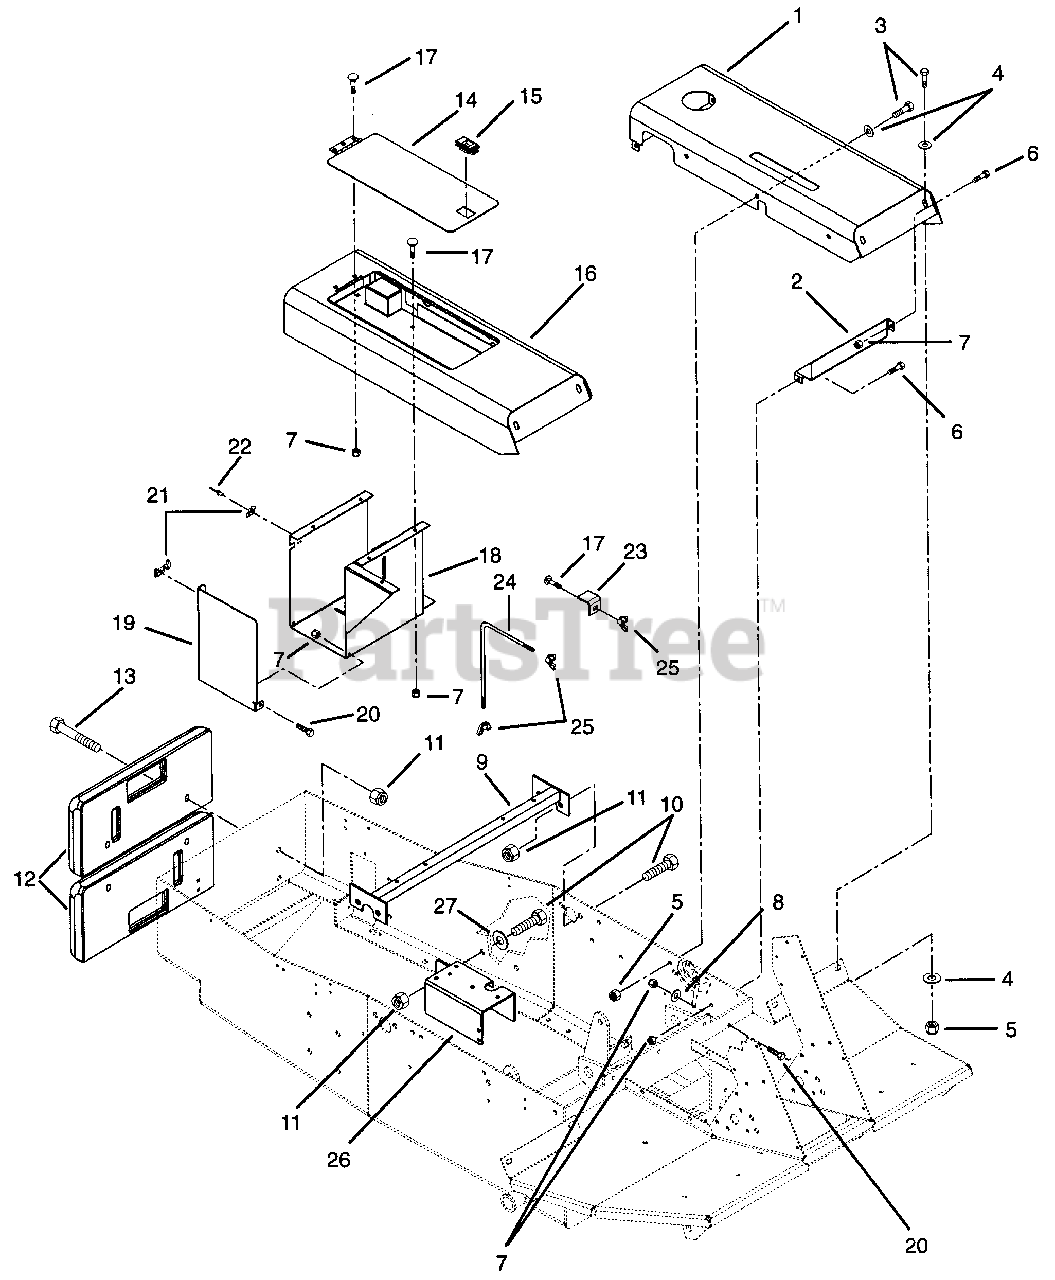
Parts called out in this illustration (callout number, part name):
1	Weldment,Left Hand Fender
2	Bracket,Fuel Tank Front Support
3	Bolt-Hex .380-16 x .875
4	Washer-Flat-Steel .406 x .812 x .065
5	Nut-Locking-Nylon .375-16 Grade 2
6	Bolt-Hex .25-20 x .75 Grade 5
7	Nut-Locking-Nylon .250-20 Grade 2
8	Washer-Flat-Steel .281 x .620 x .065
9	Weldment,Seat Cross Support
10	Bolt-Hex .50-13 x 1 Grade 5
11	Nut-Locking-Nylon .50-13 Grade 5
12	Weight,Rear Frame
13	Bolt-Hex .50-13 x 1.75
14	Weldment,Tool Box Lid
15	Latch Body
16	Weldment,Fender Right Hand
17	Bolt-Round Head Square Neck .25-20 x .75
18	Panel, Battery Holder
19	Cover,Battery Box
20	Bolt-Hex .25-20 x 1.00 Grade 5
21	Latch,Flexible
22	Rivet-Pop .125 x .232
23	Bracket,Battery Hold Down
24	Bracket,Battery Hold Down
25	Nut-Wing .250-20
26	Harness Bracket
27	Washer-Flat-Steel .531 x 1.000 x .063
